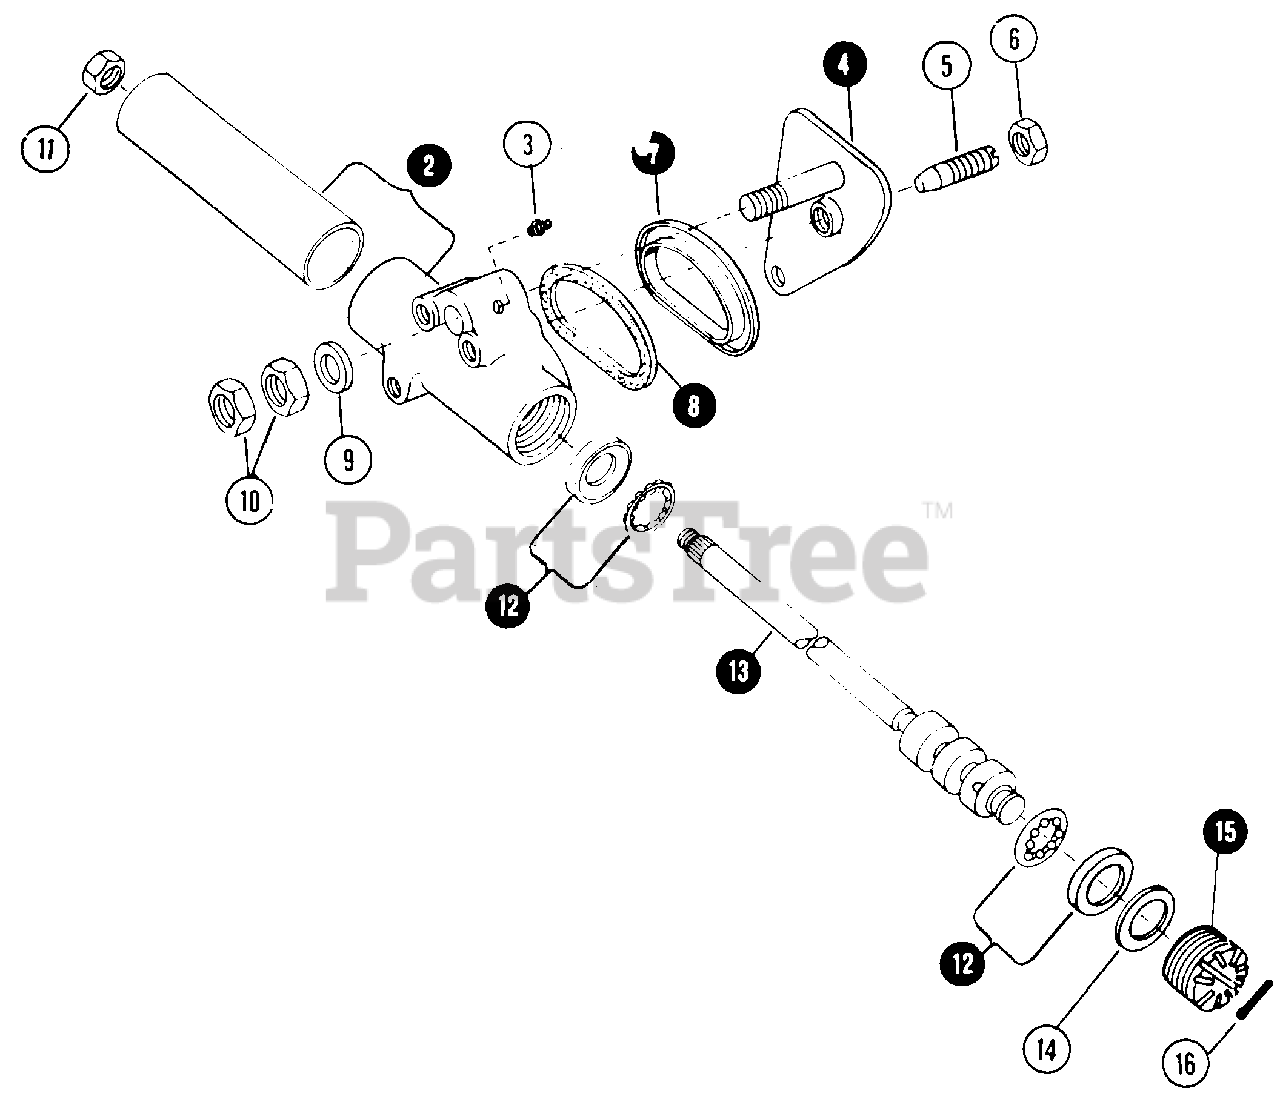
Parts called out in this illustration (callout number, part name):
2	HOUSING, STEERING GEAR
3	FITTING, GREASE 1/4 STRAIGHT DRIVE
4	LEVER, STEERING
5	STUD, STEERING LEVER ADJUSTING
6	NUT, 9/16F HEX
7	RETAINER, STEERING LEVER ADJUSTING
8	SEAL, STEERING LEVER
9	WASHER, STEERING LEVER
10	NUT, 3/4F HALF HEX
11	NUT, 5/8F HEX
12	KIT, BEARING REPLACEMENT
13	CAM-TUBE ASSEMBLY
14	WASHER, BELLEVILLE
15	PLUG, CAM-TUBE ADJUSTING
16	COTTER-PIN, 1/8 x 1/2
